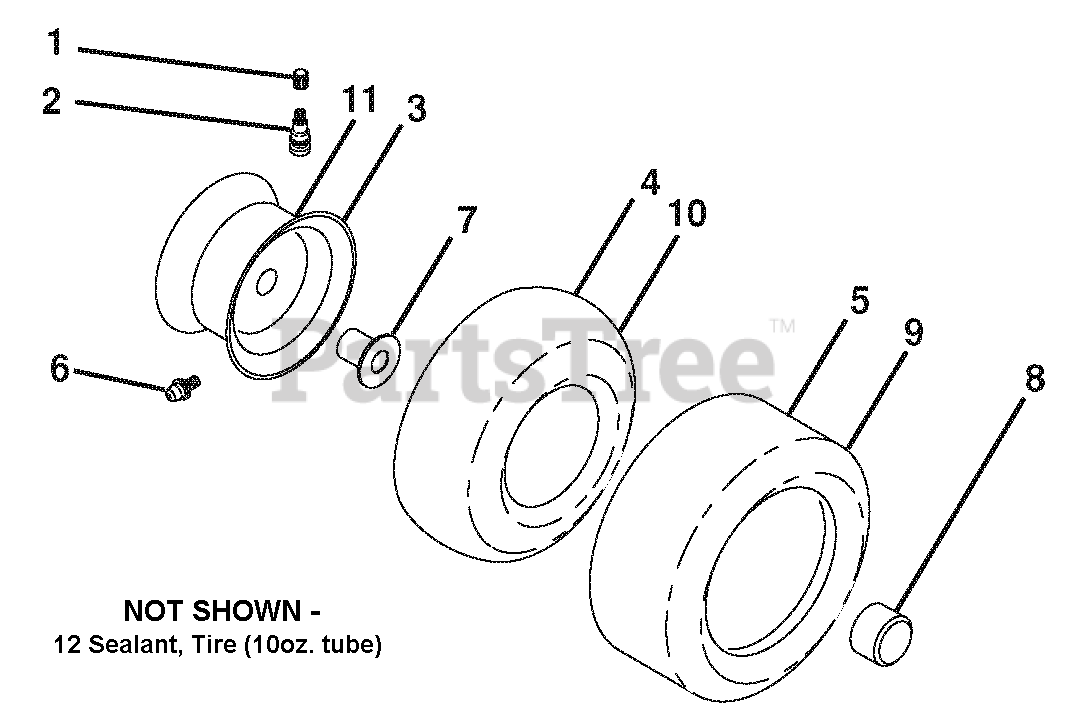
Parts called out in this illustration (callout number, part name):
1	CAP.VALVE.TIRE
2	STEM.VALVE
3	RIM ASSEMBLY 6" FRONT
4	TUBE, FRONT(SERVICE ITEM ONLY)
5	TIRE.F.TS.15 X 6.0 - 6.SERVICE
6	FITTING, GREASE
7	BEARING FLANGE
8	CAP AXLE (FRONT WHEEL ONLY)
9	TIRE.R.TS.20 X 8-8.C.SERVICE
10	TUBE, REAR
11	RIM ASSEMBLY 8" REAR
